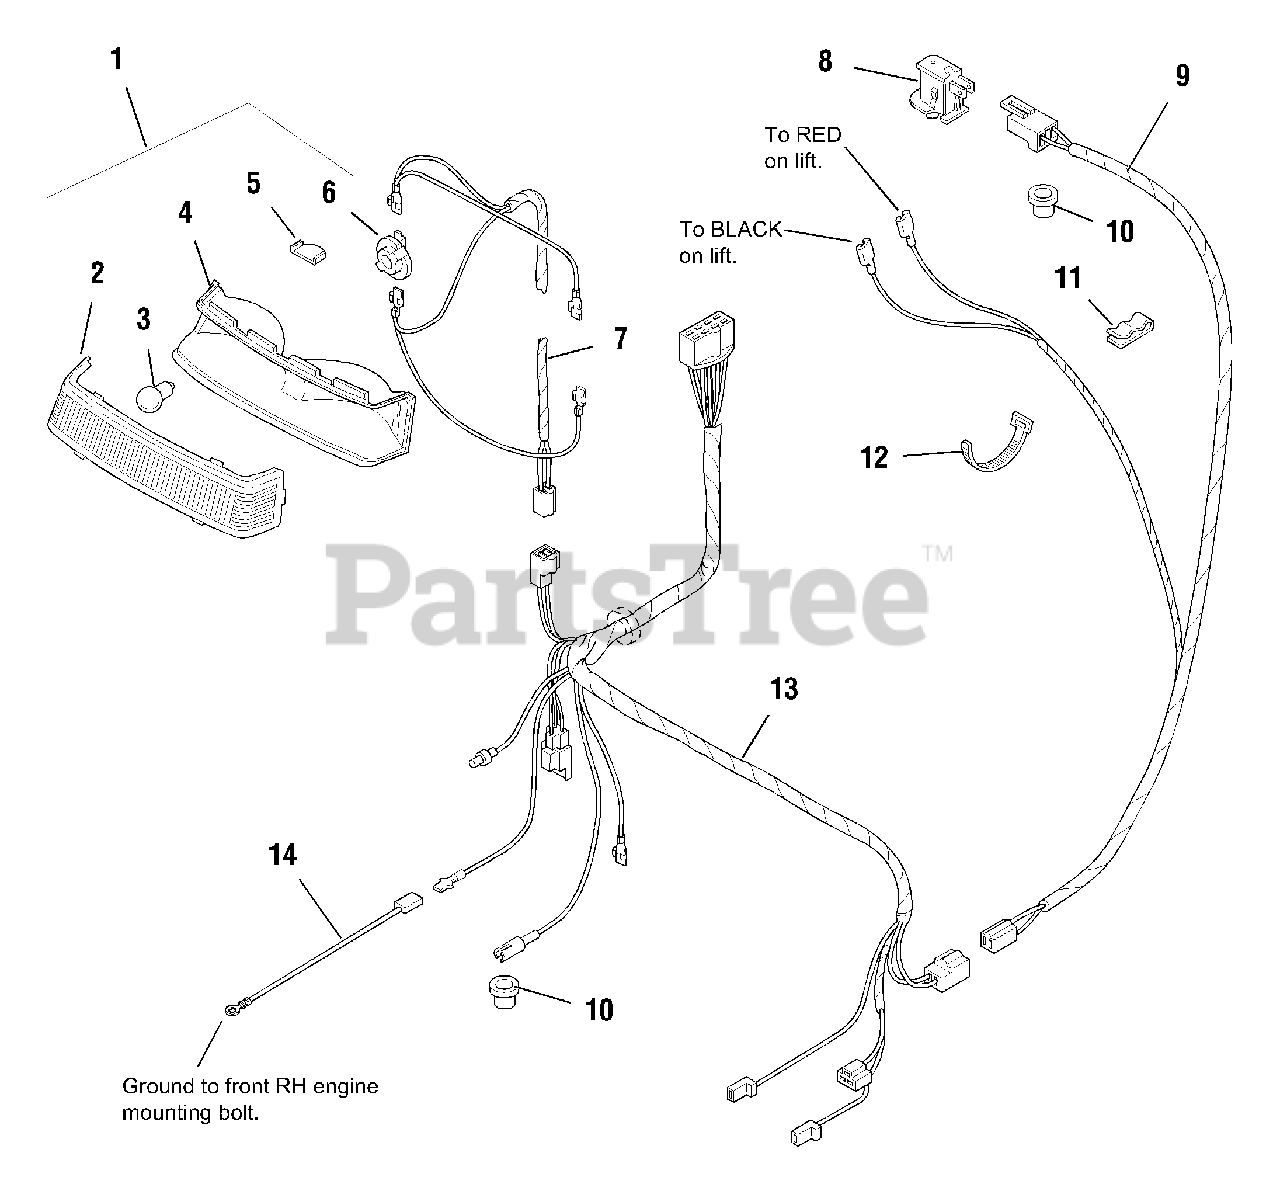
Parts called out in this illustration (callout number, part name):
1	HEADLIGHT ASSY.
2	LENS, Headlight
3	BULB, Headlight, 12.8V
4	BEZEL, Headlight
5	HEAT SHIELD
6	SOCKET, Bulb
7	WIRE ASSY., Headlight
8	SWITCH, Seat, Operator Present
9	WIRE ASSY., Seat Switch and Lift
10	BUSHING, Snap, Small
11	CLIP, Speed
13	HARNESS ASSY., Lower
14	WIRE ASSY., Engine Ground
